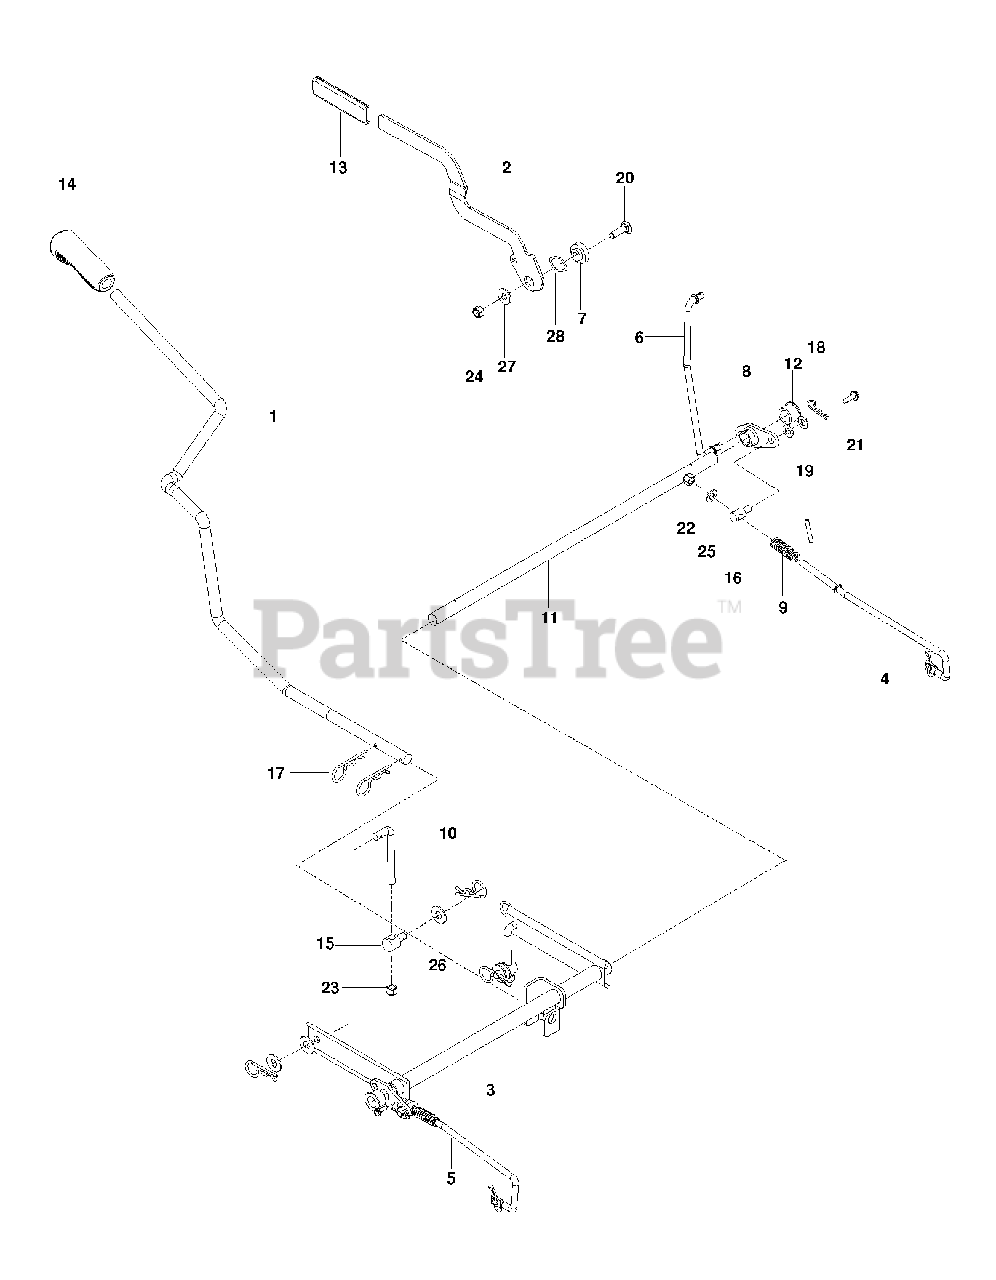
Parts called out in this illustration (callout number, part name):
1	ARM, LIFT HANDLE, BLK
2	HANDLE, BRAKE, BLK
3	SHAFT, LIFT WLDMT, BLACK
4	LINKAGE, EZT BRAKE RT
5	LINKAGE, EZT BRAKE LT
6	LINKAGE, BRAKE, UPPER
7	BRAKE ARM PIVOT
8	BELLCRANK, BRAKE
10	L ROD 3-1/8"
11	ROD, BRAKE
12	PLASTIC BUSHING
13	GRIP BRAKE HANDLE
14	GRIP.LEVER.5625.ID
16	BRAKE SWIVEL
17	HAIRPIN #4
18	HAIRPIN #2
19	ROLL PIN 3/16 X 1-1/4 ZD
20	RHSNB 3/8-16 X 1-1/4
21	SCREW #10 X 1/2 SELF TAPPING
22	NUT 5/16 NYLOC
23	NUT 3/8-16 NYLOC
24	NUT HEX 3/8-16 NYLON, THIN
25	FLAT WASHER 5/16 SAE
26	RP WASHER 3/8 FLAT
27	WASHER, 7/16 DISC SPRING
28	WASHER, .825 X 1.087, WAVE
